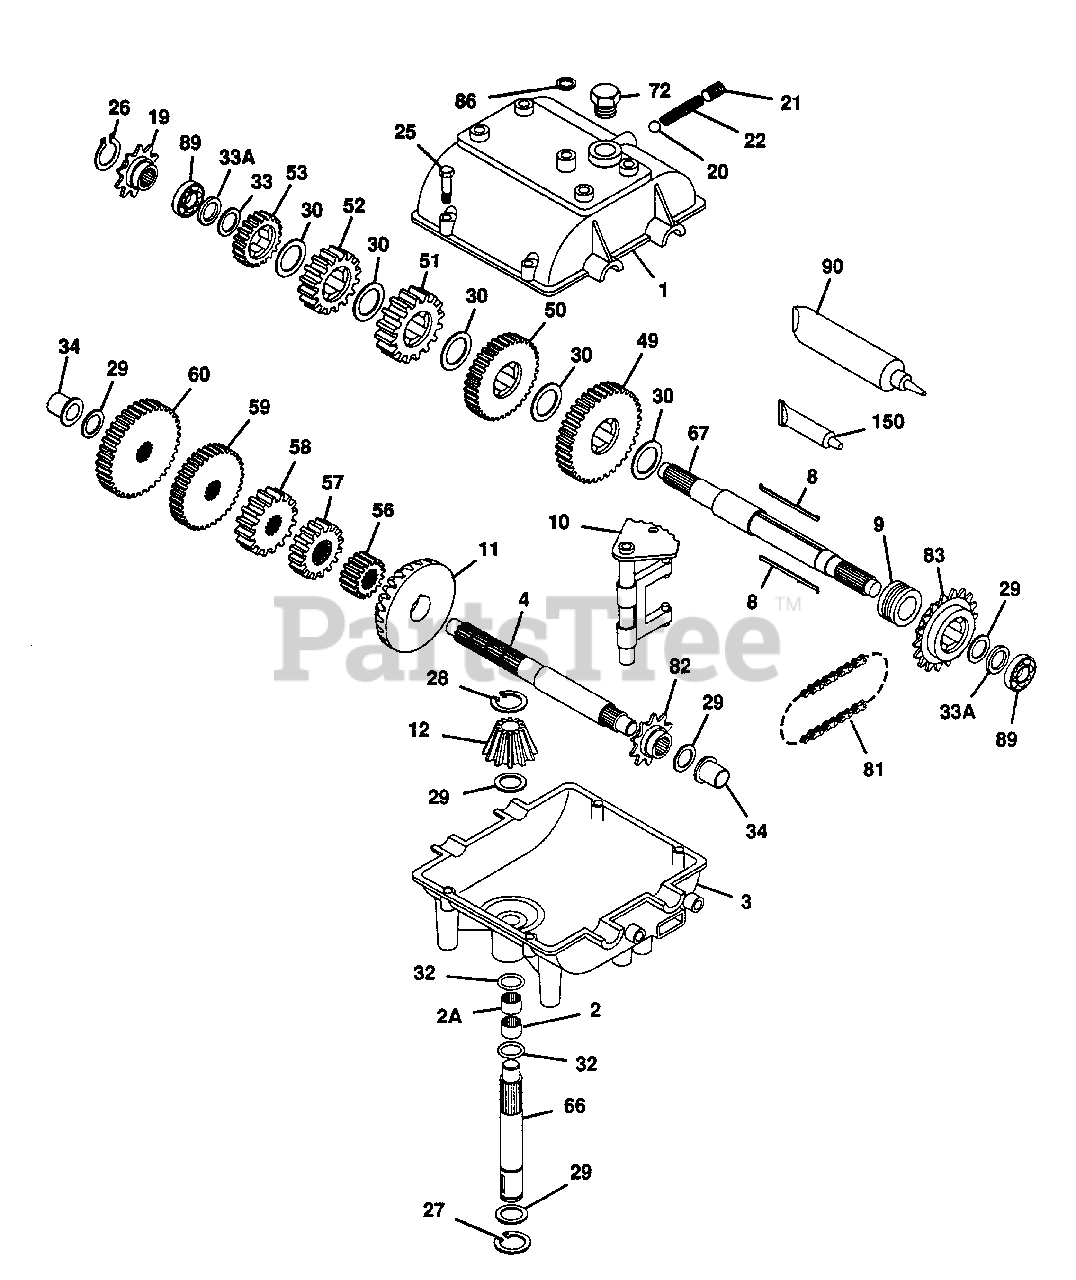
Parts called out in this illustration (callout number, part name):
1	COVER, TRANSMISSION
2	BEARING, NEEDLE
2A	BEARING, NEEDLE
3	CASE, TRANSMISSION
4	SHAFT, COUNTER
9	COLLAR, SHIFT
10	ROD & FORK ASSEMBLY, SHIFT
11	GEAR, BEVEL (42 TEETH)
12	BEVEL PINION, INPUT
19	SPROCKET (12 TEETH)
20	BALL, STEEL 5/16
21	SCREW, SET 3/8-16X3/8
25	SCREW, HHD TAPITE 1/4-20X1-1/4
26	RING, RETAINING
27	RING, RETAINING
28	RING, RETAINING
29	WASHER, THRUST
30	WASHER, THRUST
33	WASHER, THRUST
33A	WASHER, THRUST
34	BUSHING, FLANGED
49	GEAR, SPUR (35 TEETH)
50	GEAR, SPUR (30 TEETH)
51	GEAR, SPUR (25 TEETH)
52	GEAR, SPUR (22 TEETH)
53	GEAR, SPUR (20 TEETH)
56	GEAR, SPUR (15 TEETH)
57	GEAR, SPUR (20 TEETH)
58	GEAR, SPUR (25 TEETH)
59	GEAR, SPUR (28 TEETH)
60	GEAR, SPUR (30 TEETH)
66	SHAFT, INPUT
67	SHAFT, OUTPUT & BRAKE
72	PLUG, THREADED
81	CHAIN, ROLLER (NO. 41 CHAIN, 24 LINKS)
82	SPROCKET (9 TEETH)
83	SPROCKET (18 TEETH)
86	SEAL, SQUARE CUT
89	BEARING, BALL
90	GREASE (32 OZ. BOTTLE BENTONITE GREASE)
150	GASKET ELIMINATOR (LOCTITE 515)
